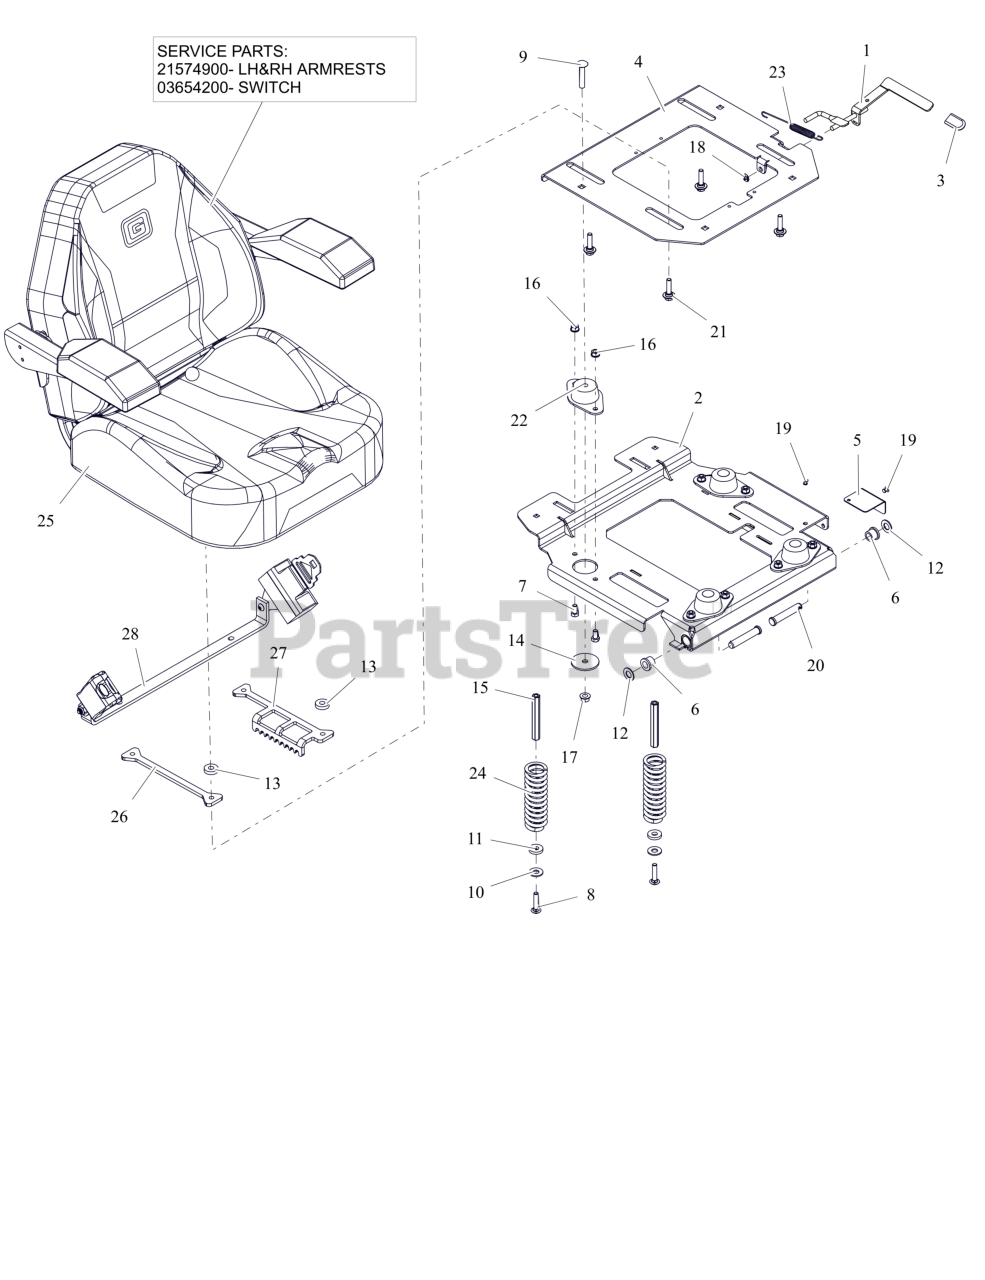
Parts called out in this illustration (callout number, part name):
1	WLDMT, SEAT SLIDE LEVER
2	WLDMT, ISO MTG PLATE (BLACK)
3	GRIP, SEAT LEVER, GREY
4	PLATE, SEAT MOUNTING (ISO KIT) (RED)
5	GUARD, SEAT FAN (SH)(BLACK)
6	BSHG, FLG .516X.750X.625X.937
7	BLT, HEX .31-18X.625 G5 ZCC
8	BLT,RHSN .31-18X1.50 G5 ZCC
9	BLT,RHSSN.375-16X2.00 G5 ZCC
10	WSHR,FLT .438X1.00X.083 ZCC
11	WSHR, FLT .406X1.00X.188 ZCC
12	WSHR, FLT .531X1.00X.063 ZCC
13	WSHR, FLT .390X1.00X.250 ZCC
14	WSHR-FL-STL 0.406X2X0.125 ZCC
15	NUT, COUPLING 5/16X18 X 3.75
16	NUT,LK-CTR-FLG .31-18 GF ZCC
17	NUT-LK-CTR-FLG .375-16 GF ZCC
18	NUT-PUSH .312
19	RIVET, .1875 AL/AL .126-.250
20	PIN, SLIC-.500X42.70X2.31 -ZC
21	BLT, SHLDR .31-18 X .175
22	MOUNT, FAIL-SAFE COMPRESSION
23	SG-TENS .06X.482X5.35
24	SPRING, COMPRESSION SEAT 224LB
25	SEAT, HD
25	LH&RH ARMRESTS
25	SWITCH- SEAT
26	PLATE, ADJ SEAT SLIDE (BLACK)
27	PLATE, SEAT ADJ (BLACK)
28	KIT-SEAT BELT REPLACE-05007300
